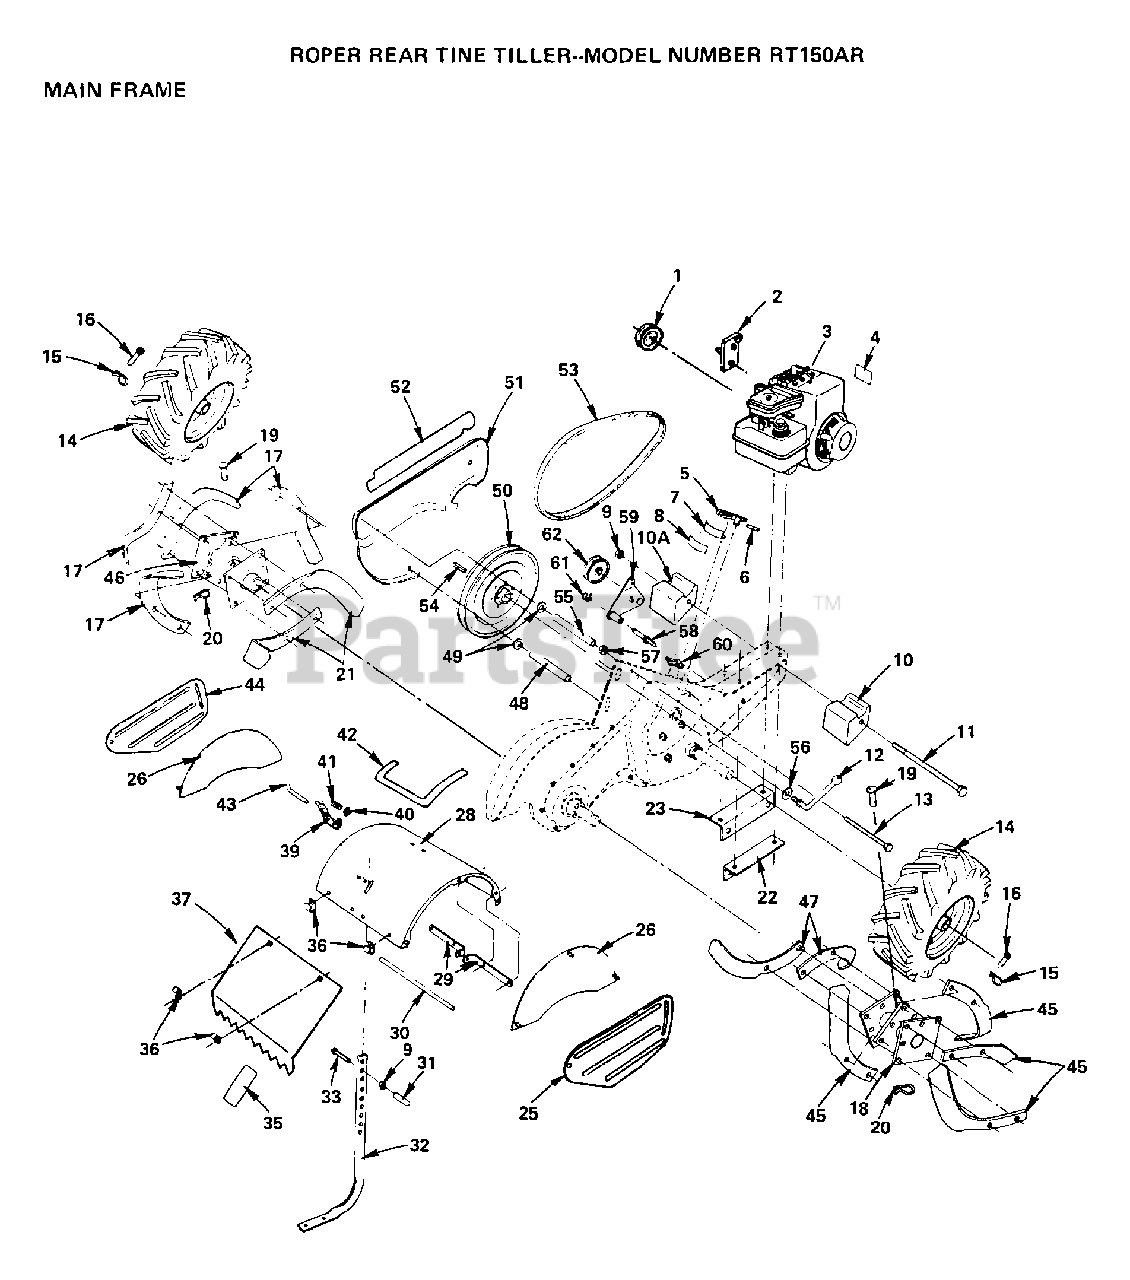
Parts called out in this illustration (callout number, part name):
2	BRACKET ASSY CRT
8	DECAL CRT
9	NUT.HEX.3/8-16UNC
10	COUNTERWEIGHT CRT
10A	COUNTERWEIGHT CRT
11	BOLT CRT
15	RETAINER M
18	TINE ASSY RH CRT
19	RIVET.PAN HD.1.75
20	RETAINER.SPRING
22	BRACKET RH CRT
23	BRACKET LH CRT
31	GRIP CRT
33	BOLT
36	HINGE CRT
37	SHLD-LEVELING TI
39	LATCH BRACKET TI
40	KLIP RING TI
41	SPRING TI
42	DECAL - TINE SHIELD
43	STAKE PIN TI
46	TINE ASSY LH CRT
50	"SHEAVE 10"" CRT"
54	KEY T
56	WASHER
57	NUT.HEX.5/16-18
58	SHIFT ARM CRT
60	CONDIUT CLIP T
61	KLIP RING
62	PULLEY-IDLER TI
